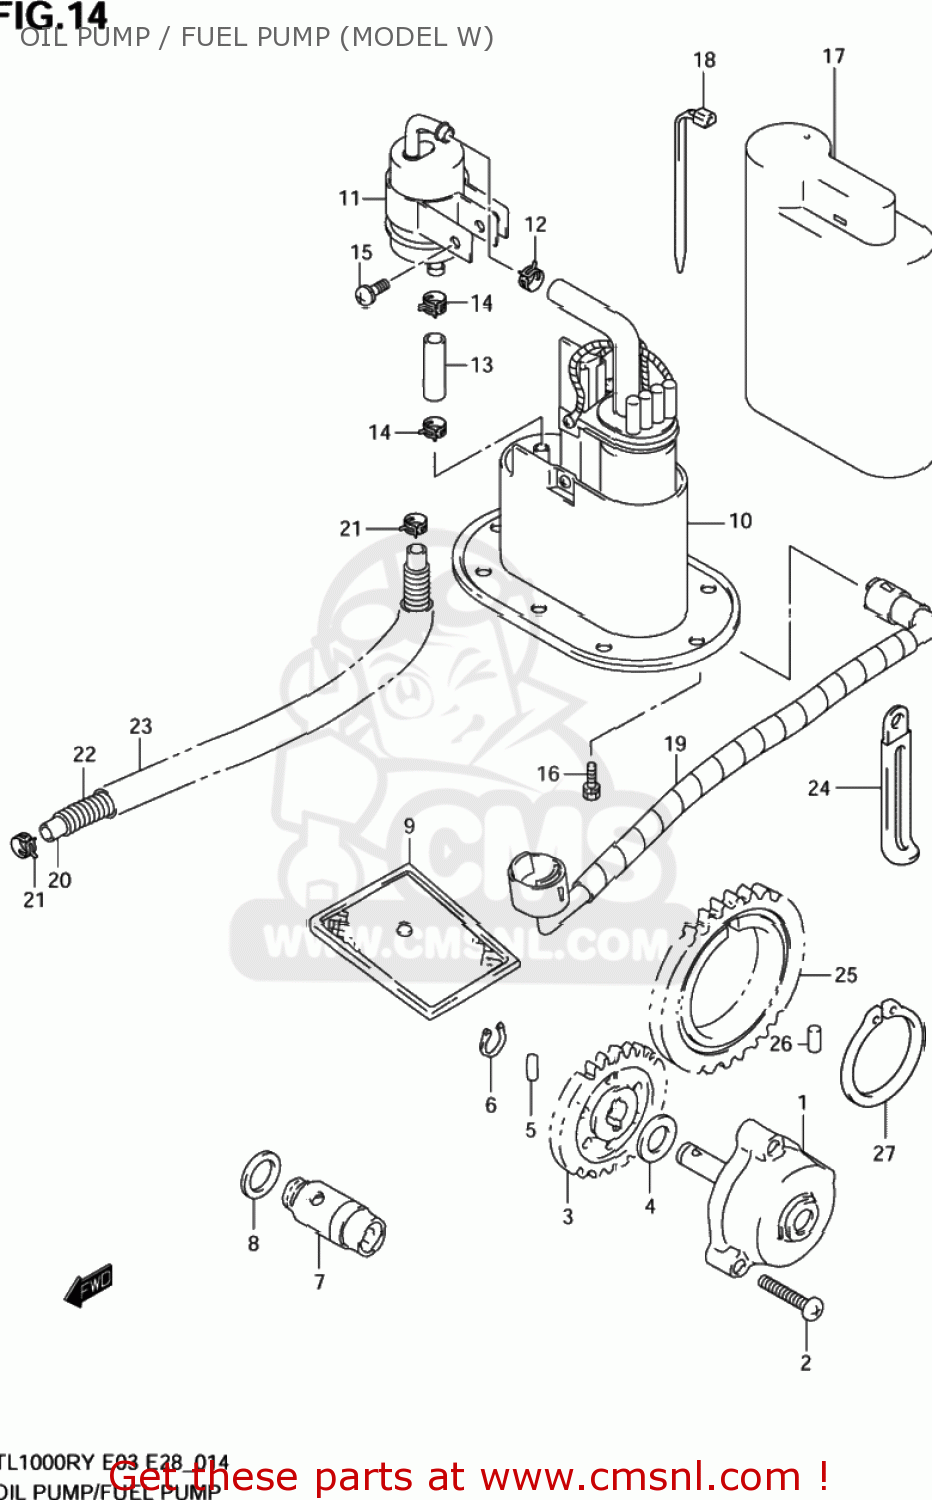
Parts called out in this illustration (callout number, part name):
1	PUMP ASSY,ENGINE OIL
2	SCREW
3	GEAR,OIL PUMP DRIVEN
4	SHIM(10X18X0.5)
5	PIN(4X15.8)
6	CIRCLIP,10MM
7	VALVE ASSY,OIL RELIEF
8	GASKET(16X22X2) (NAS)
9	STRAINER,ENGINE OIL
10	PUMP ASSY,FUEL
11	FILTER,FUEL
12	CLIP
13	HOSE(7.6X14X600)
14	CLAMP
15	SCREW
16	BOLT(5X10)
17	COVER,FUEL PUMP
18	CLAMP(L:125)
19	HOSE,FUEL
20	HOSE(5.4X11.4X600)
21	CLIP
22	(CA) SPRING
23	PROTECTOR,FUEL RETURN NO,2
24	CLAMP(L:65)
25	GEAR,ENG OIL PUMP DRIVE
26	PIN(6X6)
27	CIRCLIP
